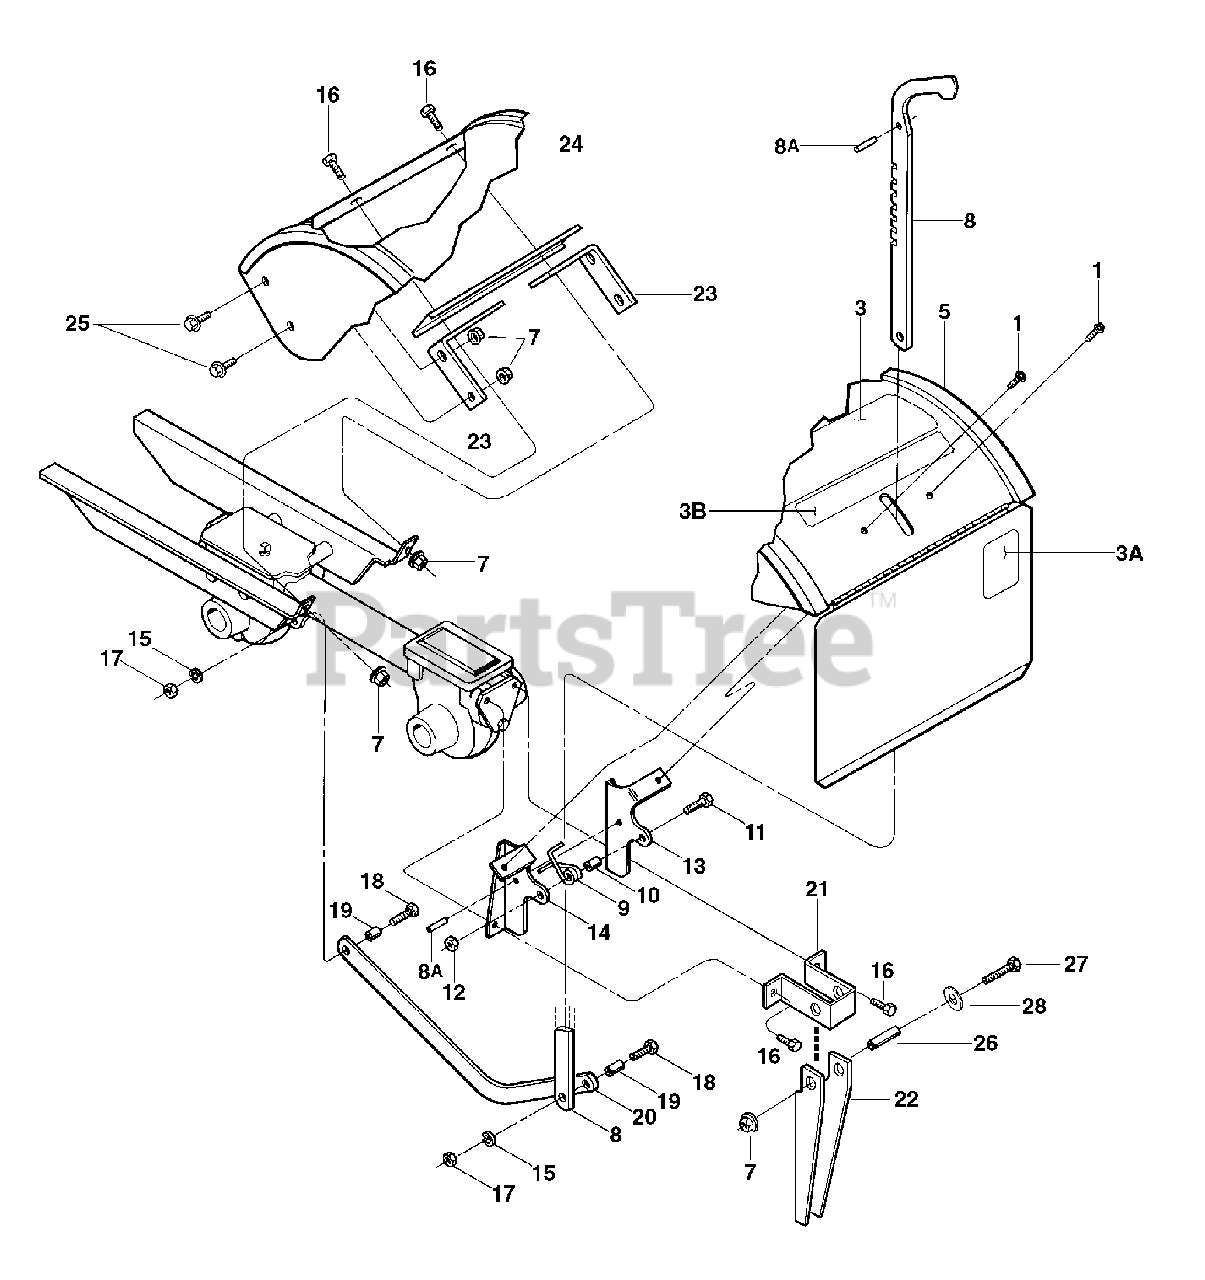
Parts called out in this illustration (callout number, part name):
1	Bolt-Fl. Hd., Self-Tap, 1/4-20 x 1/2
3	Decal-Hood
3A	Decal-Warning
3B	Decal-Logo
5	Tine Hood,
7	Nut-Flange Lock, 5/16-18
8	Depth Regulator Lever
8A	Spirol Pin
9	Spring-Depth Regulator
10	Spacer
11	Bolt-Hex Hd., 1/4-20 x 1
12	Locknut-Hex Hd., 1/4-20
13	Bracket-Hood, Right Hand
14	Bracket-Hood, Left Hand
15	Lockwasher, 5/16
16	Bolt-Flanged Hd., 5/16-18 x 1
17	Nut-Hex Hd., 5/16-18
18	Bolt-Hex Hd., 5/16-18 x 1-1/4
19	Bushing-Drag Bar
20	Drag Bar
21	Bracket-Stop
22	Arm-Reverse (Drag Stake)
23	Bracket-Hood Support
24	Bracket-Support Channel
25	Bolt-Hex Hd. 5/16-18 x 5/8
27	Bolt-Hex Hd. 5/16-18 x 2-1/4
28	Washer-5/16 I.D.
